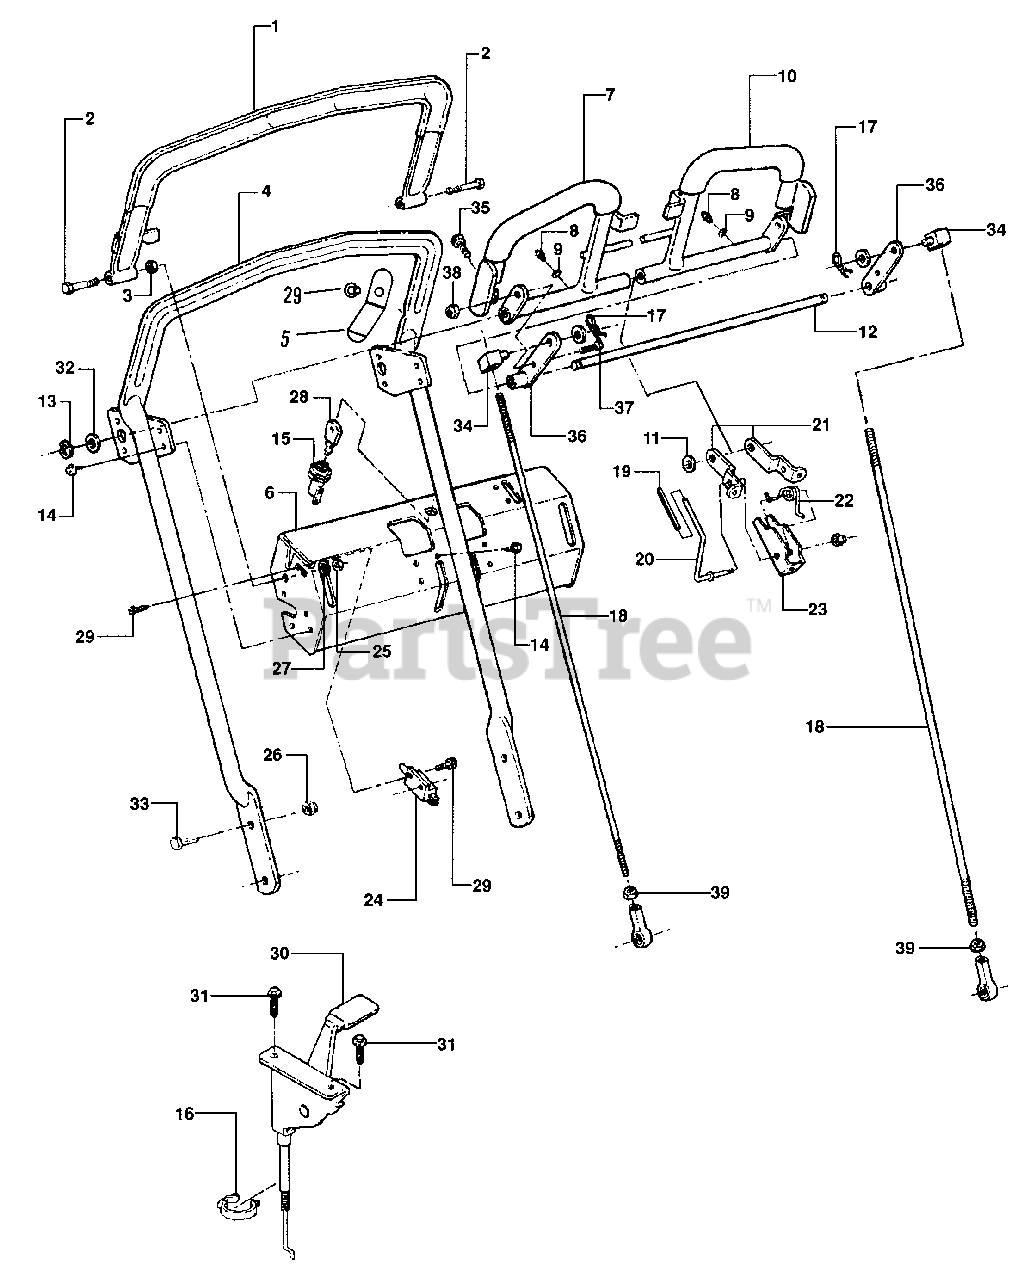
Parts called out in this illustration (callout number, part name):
1	BAIL, OPC (With Grip)
2	BOLT, 1/4-20 X 1-1/2" Hex Head
3	NUT, 1/4-20 Hex
4	HANDLE, Loop
5	SPRING
6	CONTROL, Console
7	LEVER, Traction (Right Hand With Grip)
8	ZERK, 1/4-28
9	WASHER, 1/4" Internal Tooth Lock
10	LEVER, Traction (Left Hand With Grip)
11	WASHER, 1/2" Flat
12	ROD, Pivot
13	"E"-RING, 1/2"
14	SCREW, 1/4-20 X 1/2" Self Tapping
15	SWITCH, On-Off
16	CLIP, Cable
17	HAIR PIN, Cotter
18	ROD, Traction
19	GRIP, Neutral Latch Red
20	LEVER, Neutral Latch
21	BRACKET, Neutral Mounting
22	SPRING, Neutral Torsion
24	SWITCH, OPC
25	NUT, 1/4-20 Nyloc
26	NUT, 3/8-16 Nyloc
27	WASHER, 1/4" Flat
28	KEY, Switch (With Cover)
29	SCREW, #12-14 X 1/2" Self Tapping
30	CONTROL, Throttle (Kawasaki)
31	SCREW, #10-24 x 1/2" Hex Washer Self-Tap (Torx)
32	BUSHING, 1/2" Machine
33	SCREW, 3/8-16 X 1" Hex Head
34	SWIVEL
35	SCREW, 1 /4-20 X 3/4"
36	TRACTION ARM
37	SCREW, 5/16-18 X 1" Hex Head
38	NUT, 5/16-18 Nyloc
39	NUT, 5/16-24 Hex
